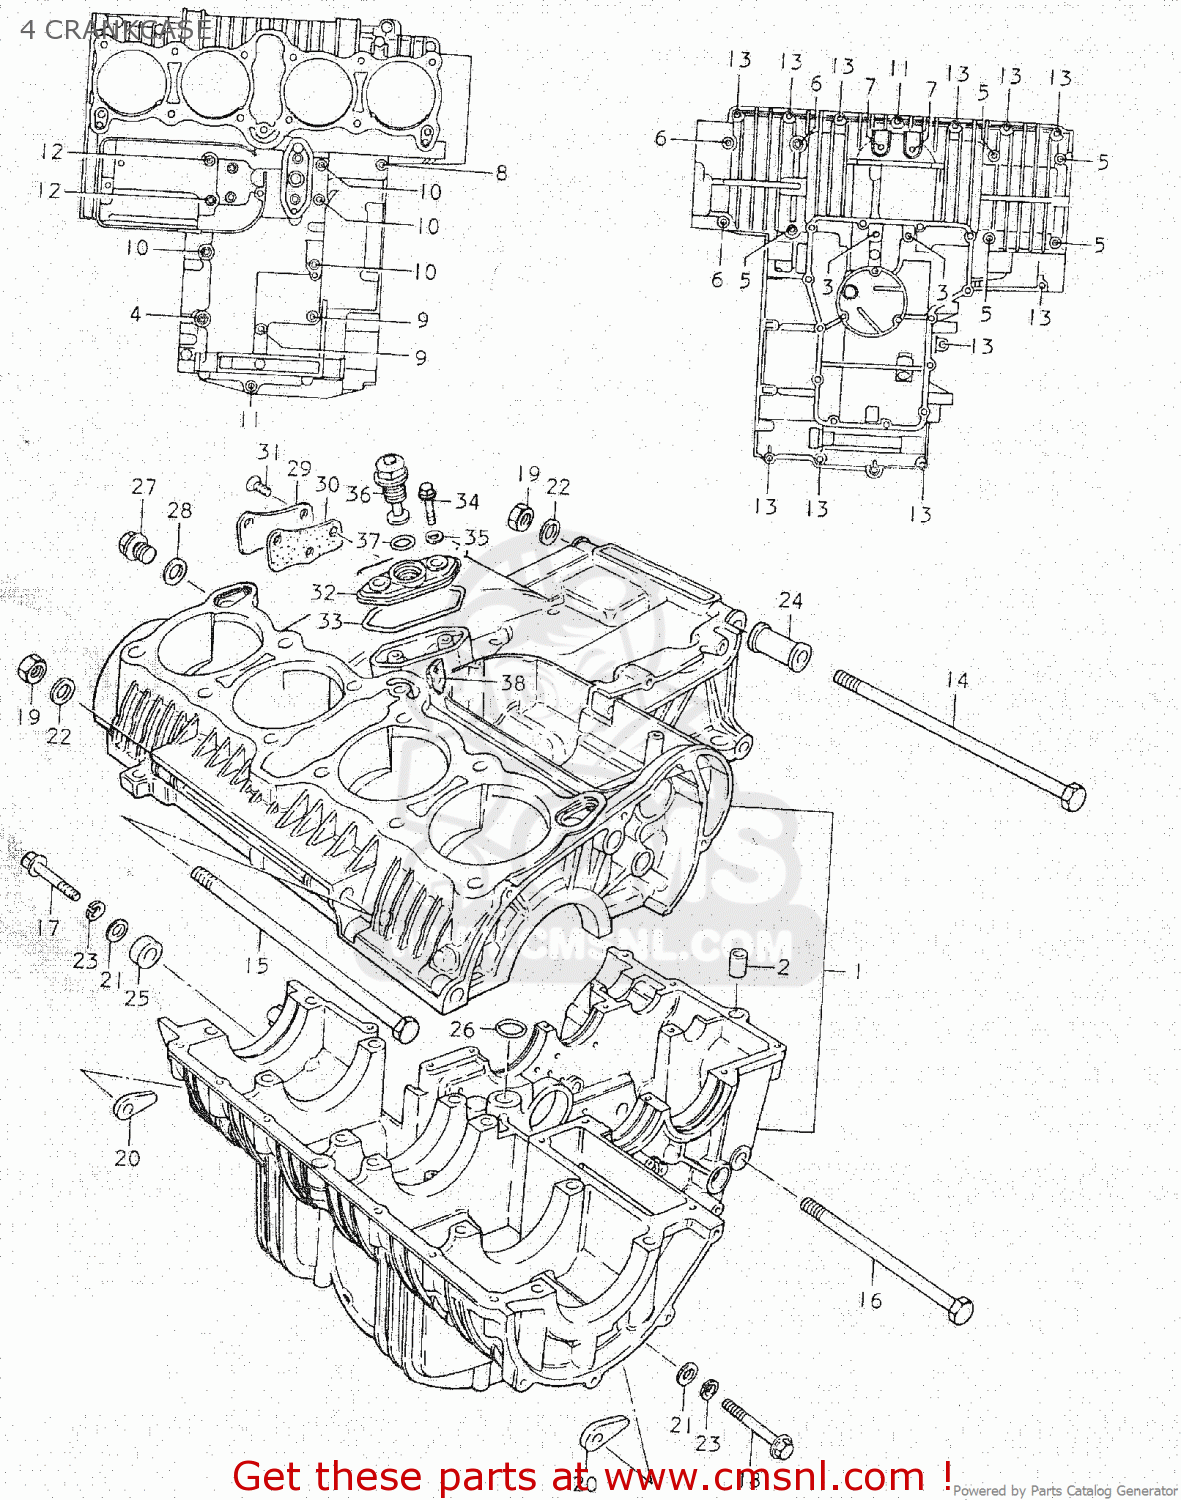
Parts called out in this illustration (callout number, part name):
1	CRANKCASE SET
2	PIN
3	BOLT
4	BOLT (8X95)
5	BOLT 8X90
6	BOLT 8X65
7	BOLT
8	BOLT 6X100
9	BOLT (6X90)
10	BOLT (6X80)
11	BOLT
12	BOLT,UNDER
13	BOLT
14	BOLT 10X250
15	BOLT 10X235
16	BOLT 10X160
17	BOLT 10X65
18	BOLT 10X55
19	NUT
20	NUT
21	WASHER(10.5X20X3.2)
22	WASHER
23	LOCK WASHER
24	SPACER
25	SPACER (10.2X24X11)
26	O RING(D:3.2,ID:12.9)
27	PLUG (14X12)
28	GASKET(14X19.2X2) (NAS)
29	CAP,OIL GALLERY
30	GASKET,OIL GALLERY (MCA)
31	SCREW
32	HOUSING,OIL PRESSURE SWITCH
33	O RING,PRESSURE SWITCH HOUSING
34	BOLT
35	GASKET (NAS)
36	SWITCH ASSEMBLY
37	O RING(D:1.9,ID:18.8)
38	GROMMET,STARTING MOTOR
